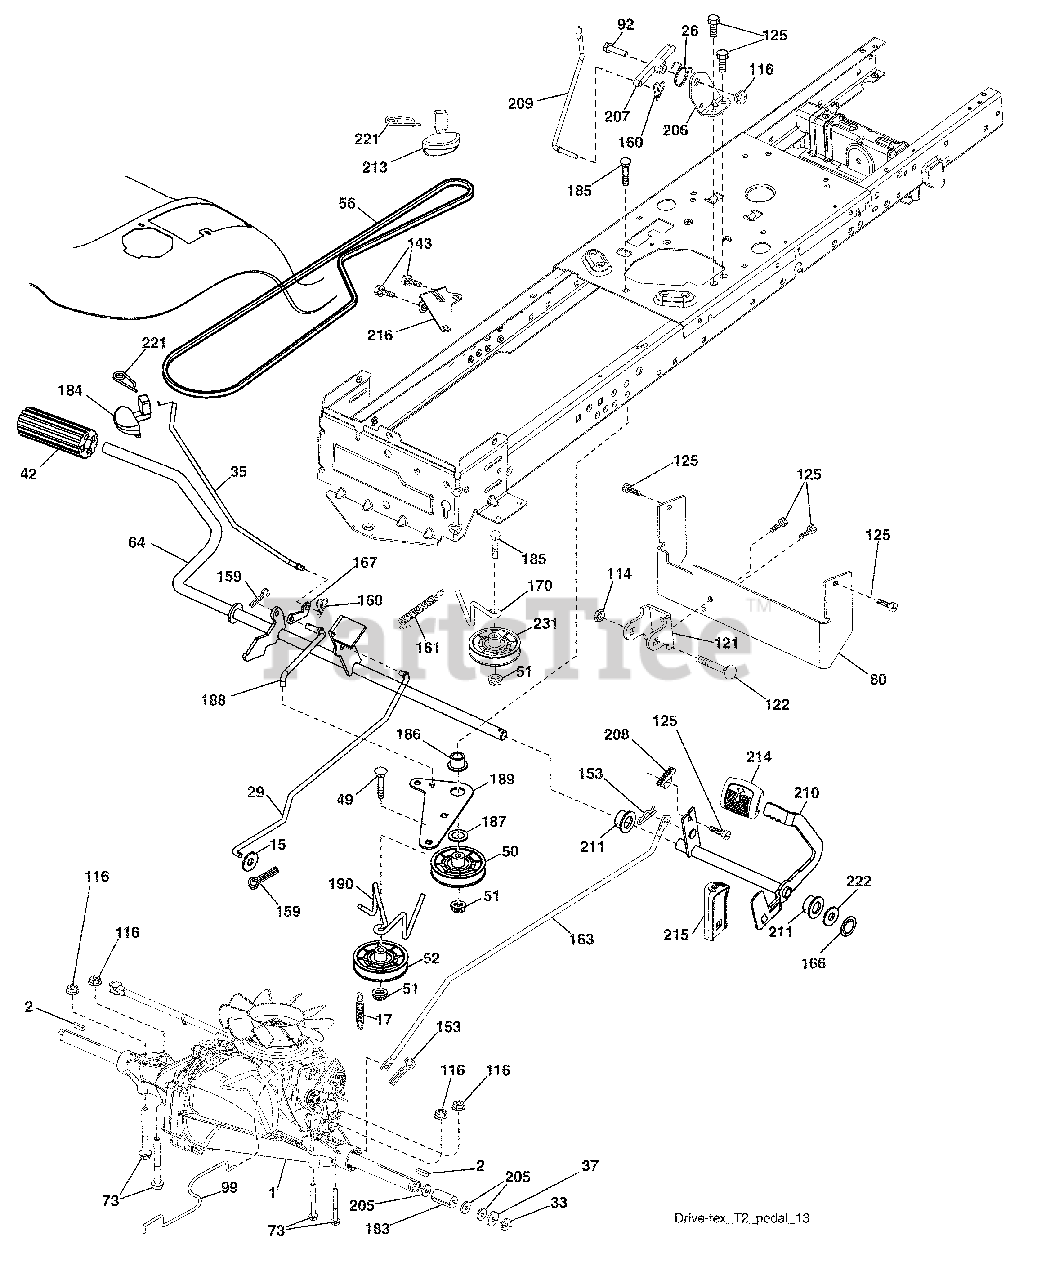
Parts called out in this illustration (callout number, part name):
15	Washer 13/32 x 13/16 x 16 Ga.
17	Spring, Brake
26	Spring Return Cruise
29	Rod, Brake
35	Rod, Brake, Park
37	Washer 25/32 x 1-1/4 x 16 Ga.
42	Cover, Foot Pedal
50	Pulley Idler Flat
51	Lock Nut 3/8-16
52	Idler V-Groove 910" Offset
56	V-Belt, Drive
64	Shaft Asm. Pedal Brake Control
73	Bolt 5/16-18 Gr. 5
80	Strap Torque
92	Bolt Fin Hex 5/16-18 unc x 1.25
99	Rod Asm Bypass Spring
114	Nut Lock 5/16-18 unc
116	Nut Lock Hex Flange 5/16-18
121	Bracket Strap Torque
122	Bolt 5/16-18 x 2.50
125	Screw 5/16-18 x 3/4
143	Screw THDROL 5/16-18 x 1/2
153	Retainer Spring
159	Pin Cotter 1/8 x 3/4
160	Retainer Clip
161	Spring, Return, Clutch
163	Rod Pedal Control
166	Nut Push .625
167	Latch Brake Parking
170	Keeper Belt Centerspan
183	Spacer Axle
184	Handle Parking Brake
186	Spacer Retainer
187	Washer
188	Link Clutch Ground Drive
189	Bellcrank Ground Drive
190	Keeper Bellcrank Ground Drive
205	Washer 25/32 x 1-5/8 x 16 Ga.
206	Bracket Mount Latch Cruise
207	Latch Control Cruise
208	Gear Sector Control Cruise
209	Rod Control Cruise
210	Rocker Asm. Pedal Control
211	Bearing Nylon
213	Knob Control Cruise
214	Pad Pedal Forward
215	Pad Pedal Reverse
216	Braket Pulley Idler
221	Retainer Spring Clip Handle
222	Washer 21/32 x 1-1/4 10 Ga.
231	Idler V-Groove 1.688
